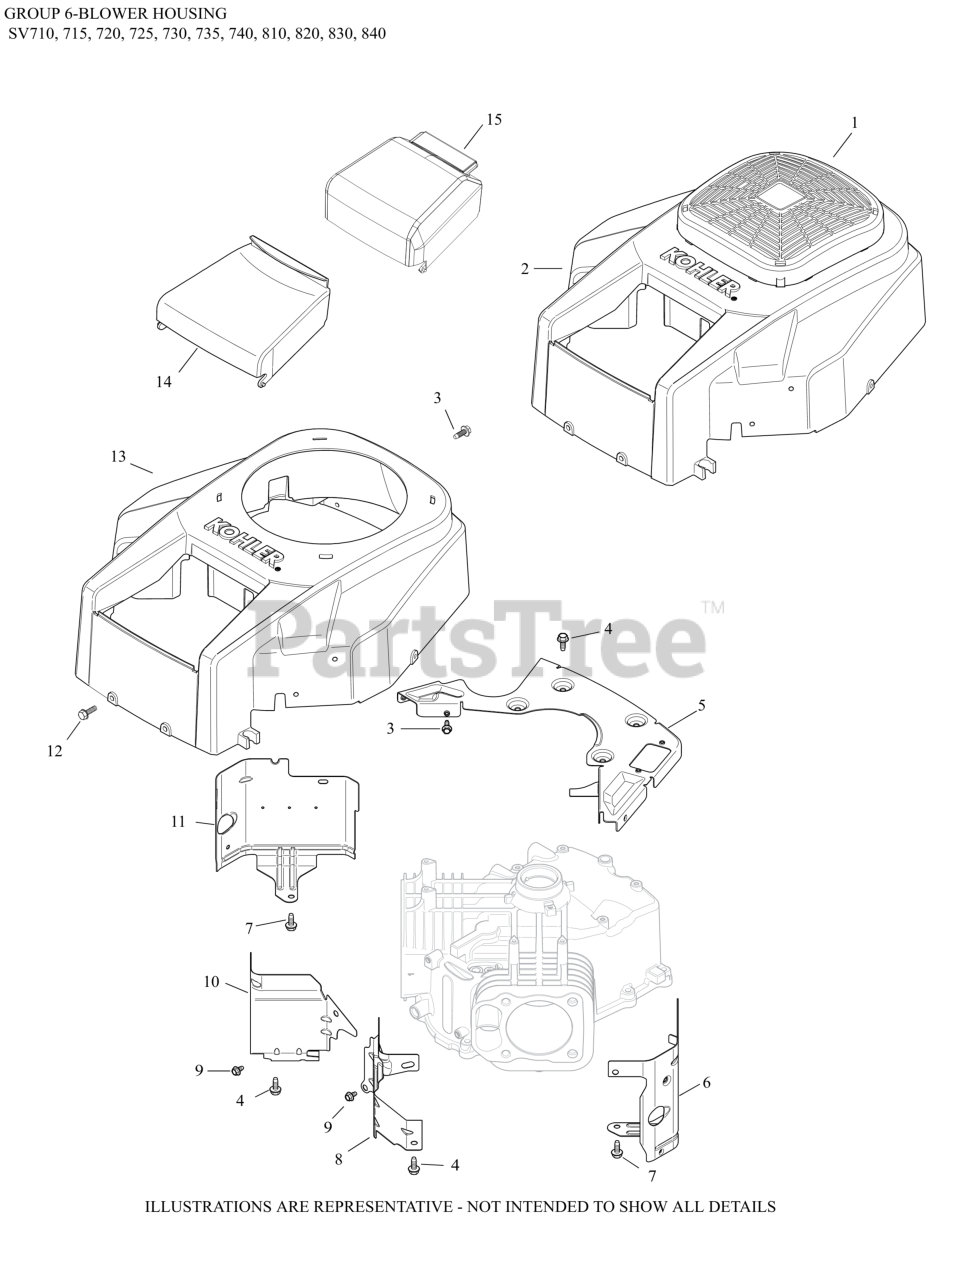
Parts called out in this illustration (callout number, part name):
3	SCREW, THREAD FORMING
4	SCREW, THREAD FORMING
5	KIT, BACKING PLATE-(#DSC)
6	BAFFLE, LEFT BARREL
7	SCREW, THREAD FORMING
8	BAFFLE, VALLEY #2 CYLINDER
9	SCREW, THREAD FORMING
10	BAFFLE, VALLEY #1 CYL-USE 24 063 114-S
11	BAFFLE, CYL BARREL - #1 SIDE
12	SCREW, TAP M6X1.7X18
13	KIT, HOUSING BLOWER-(#DSC)
14	COVER, AIR CLEANER
